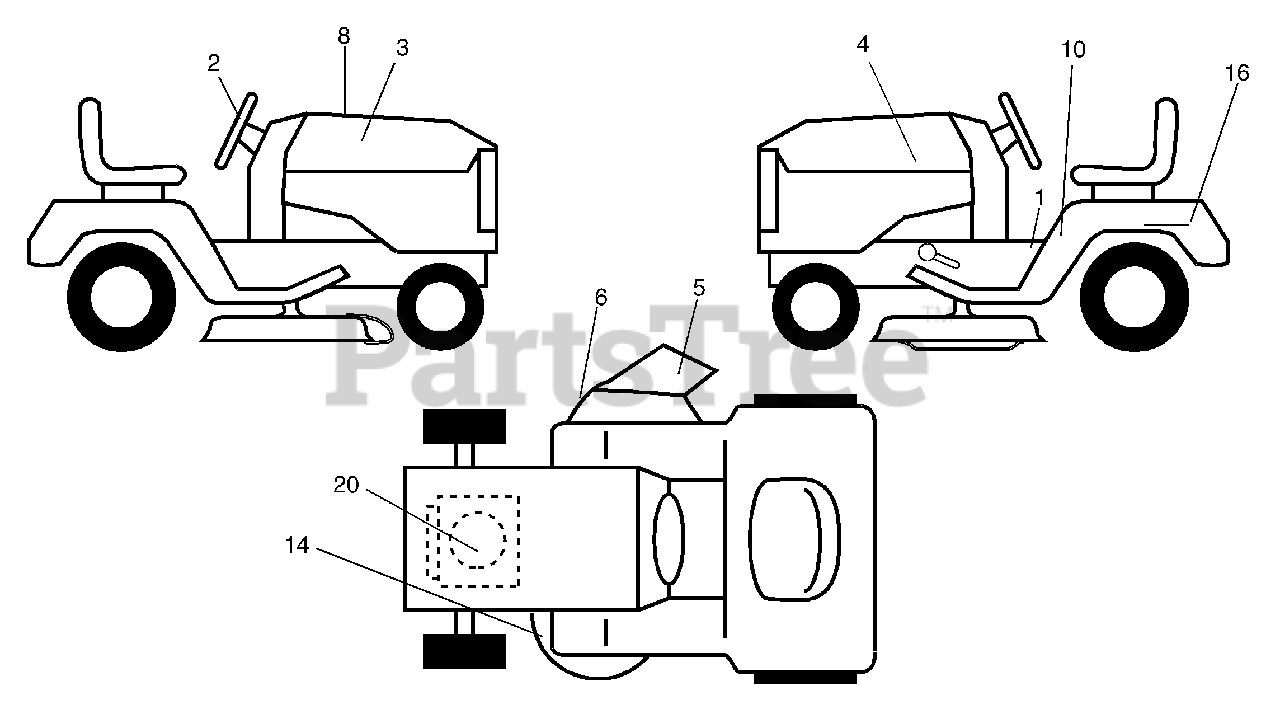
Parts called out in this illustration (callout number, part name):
1	Decal Instruction Operat English
2	Decal Steering Wheel
3	Decal Hood Rh
4	Decal Hood Lh
5	Decal Deck "B"
6	Decal Warning
8	Decal Replacement Parts
10	Decal Danger English
14	Decal V-belt Schematic 42"
16	Decal Battery Danger/Poison
20	Decal HP Engine
